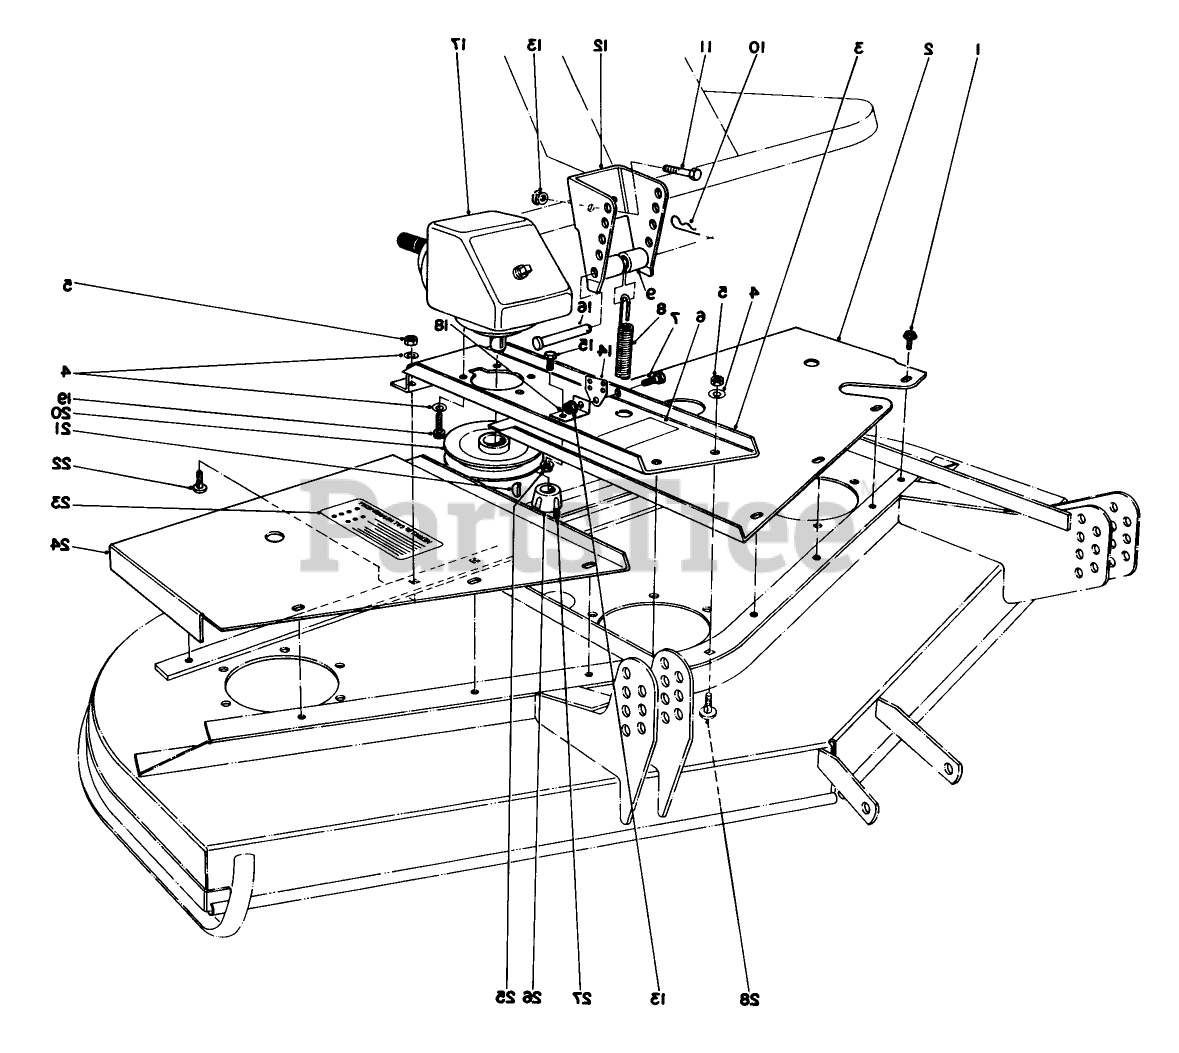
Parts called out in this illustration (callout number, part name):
1	SCREW-HHFTF
2	RH COVER WA R
3	Base-Bear Box
4	WASHER-LOCK
5	NUT-HEX
6	Decal-Caution
7	BOLT-SHOULDER
8	Spring-Extension
9	SPACER
10	PIN-HAIR
11	SCREW-HH
12	SPRING BRACKET R
13	NUT-HHF, WHIZ
14	SPRING END R
15	SCREW-HH
16	PIN-CLEVIS
17	GEAR BOX ASM
18	EXTENSION BRKT R
19	SCREW-HSH
20	PULLEY WA BO
21	KEY-WOODRUFF
22	BOLT-CARR
23	DECAL
24	LH COVER WA R
25	NUT-HF
26	BUSHING-LOCK, TAPER
27	SCREW-SET, HSH
28	SCREW-CARR
